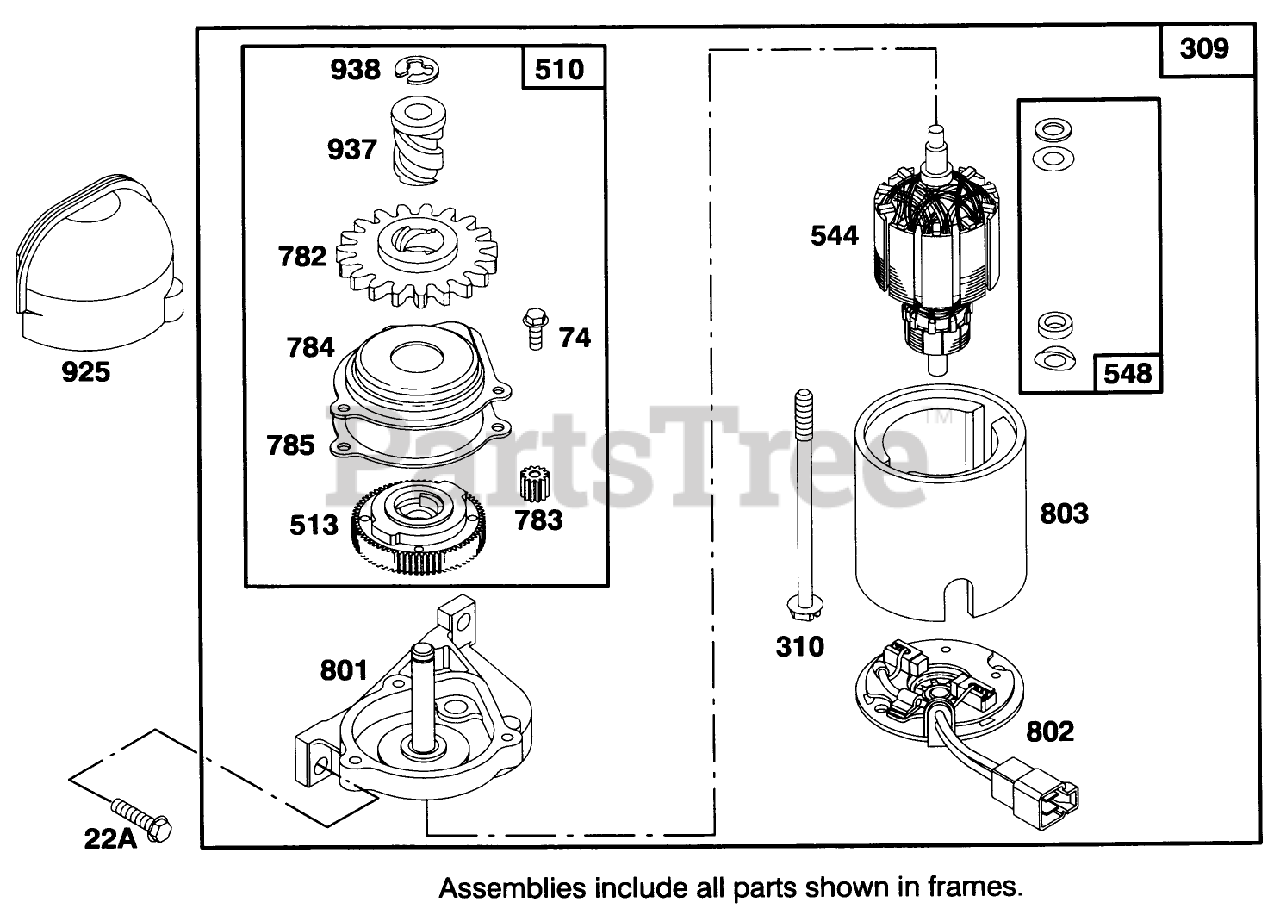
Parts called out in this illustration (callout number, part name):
22A	SCREW - CARBUERTOR MTG
510	DRIVE SET
513	CLUTCH - STARTER
548	WASHER ASSEMBLY
782	GEAR - STARTER
925	COVER - STARTER
938	RETAINER - LOCK
